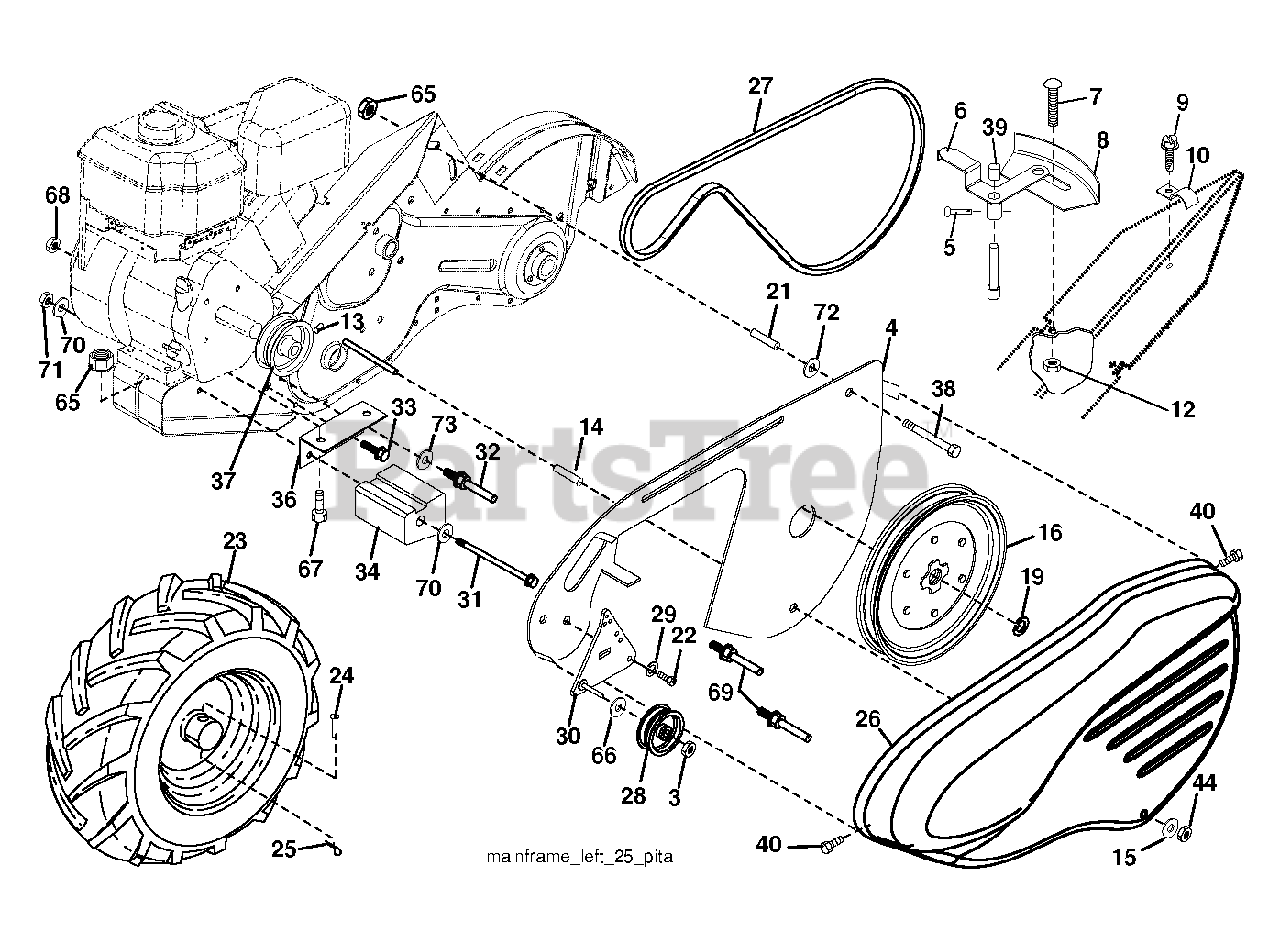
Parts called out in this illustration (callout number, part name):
3	LOCKNUT
5	PIN.SPIROL.FLARED
6	LEVER ASM CRT
9	TAPPING SCREW
10	CLIP.PLATED
12	NUT
13	SET SCREW **
14	SPACER-SPLIT.327 X .42
15	WASHER.FLAT.34X1.38X22
16	SHEAVE, TRANSMISSION
19	RETAINING RING LT
21	SPACER SPLIT
23	WHEEL.ASM.16X4X8.DR.LH.417
24	RIVET
25	RETAINER M
27	V-BELT
28	PULLEY-IDLER TI
29	KLIP RING
30	Idler Assembly Bracket, Long
31	BOLT.FIN.HEX.3/8-16UNC X 11.5
32	SHIFT ARM CRT
33	BOLT
34	COUNTERWEIGHT.LH
37	ENGINE PULLEY
38	BOLT
39	CAP.PLUNGER.BLACK
40	SCREW.HEX.WSH.SLT.#10-24X.50
44	NUT.71038.31-18.HEX.NYLOCK
65	LOCKNUT-FLANGE 5/16-18
67	BOLT, HEX 5/16-18X1-3/4
69	KEEPER.BELT.ENGINE
71	LOCKNUT
73	WASHER
